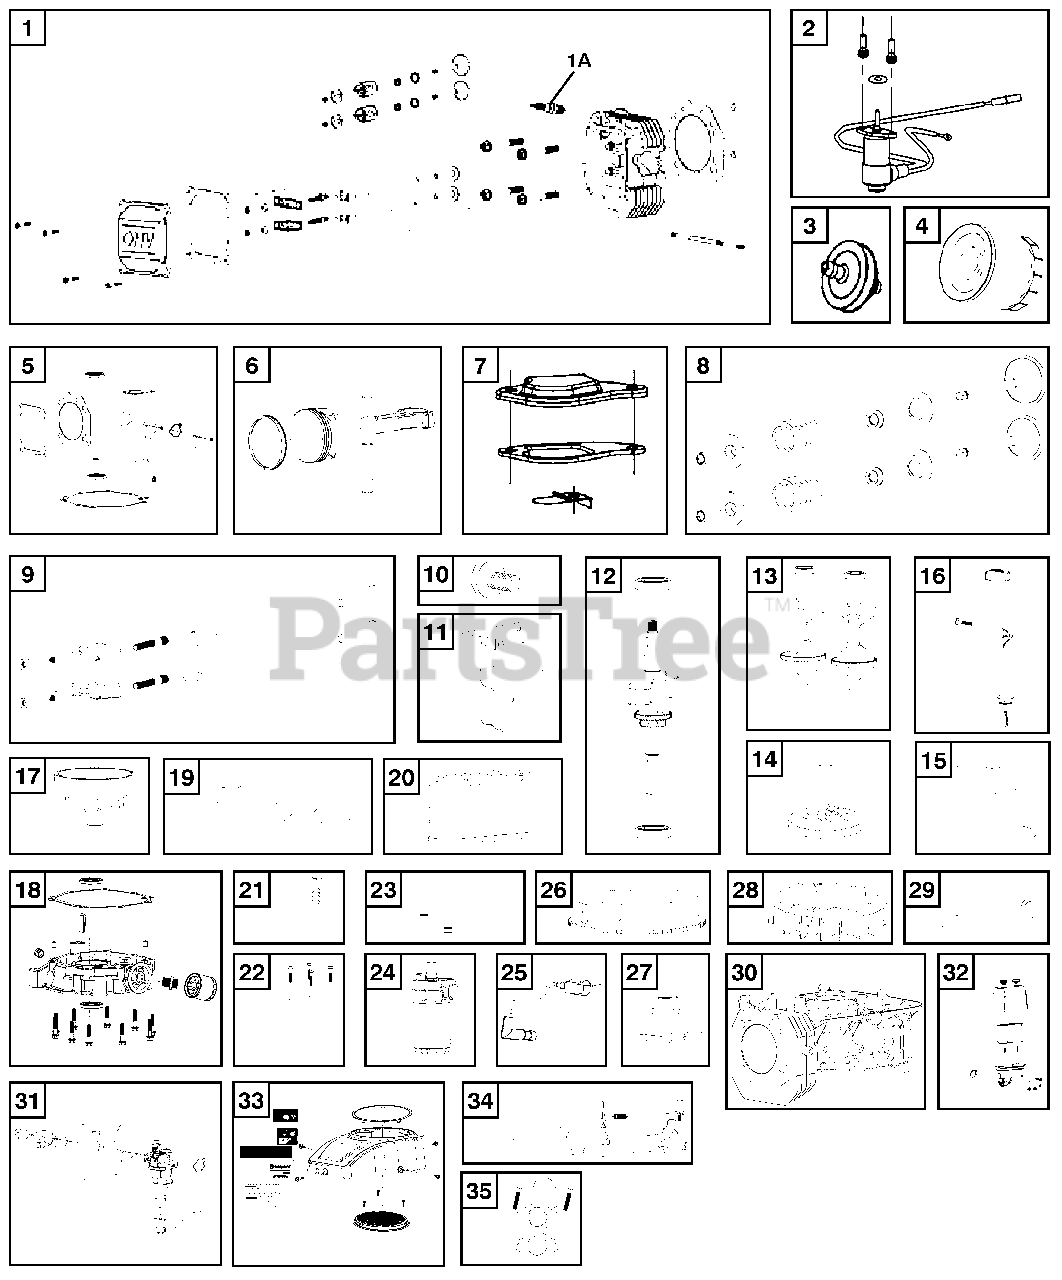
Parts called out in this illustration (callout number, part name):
1	SERVICE KIT CYLINDER HEAD COMP
1A	Spark Plug
2	SERVICE KIT SOLENOID KIT
3	Fuel Filter
4	Oil Filter
5	SERVICE KIT GASKET AND SEAL KI
6	SERVICE KIT PISTON AND RING KI
7	SERVICE KIT COVER COMP BREATHE
8	SERVICE KIT KIT.VALVE (KIT 10)
9	SERVICE KIT KIT.ROCKER.ARM. (K
10	SERVICE KIT KIR.HEXAGON.BOLT W
11	SERVICE KIT KIT.AIR.DEFLECTOR
12	SERVICE KIT KIT.CRANKSHAFT (KI
13	SERVICE KIT KIT.BALANCING.SHAF
14	SERVICE KIT KIT.CRANKSHAFT.ASS
15	SERVICE KIT KIT.OIL.STRAINER (
16	SERVICE KIT KIT.FILL.TUBE (KIT
17	SERVICE KIT KIT.COMPONENTS OF
18	SERVICE KIT KIT.CRANKSHAFT.COV
19	SERVICE KIT KIT.SPEED REGULATI
20	Air Filter
21	SERVICE KIT KIT.PRESSING PLATE
22	SERVICE KIT KIT.CHARGING AMATU
23	SERVICE KIT KIT.VOLTAGE.RECTIF
24	SERVICE KIT KIT.STARTER.MOTOR.
25	SERVICE KIT KIT.COIL.IGNNITION
26	SERVICE KIT KIT.STARTING .DISC
27	SERVICE KIT KIT.STARTING DISC.
28	SERVICE KIT KIT.IMPELLER (KIT
29	ACCESSORY BAG LIT.PACK.9676719
30	SERVICE KIT KIT.CRANKCARE.BODY
31	CARBURETTOR CARBURETOR.KIT
32	SERVICE KIT KIT.AIR.CLEANER
33	SERVICE KIT KIT.START.COVER.KI
34	SERVICE KIT KIT.THROTTLE.KIT
35	SERVICE KIT KIT.EXHAUST.PIPE
